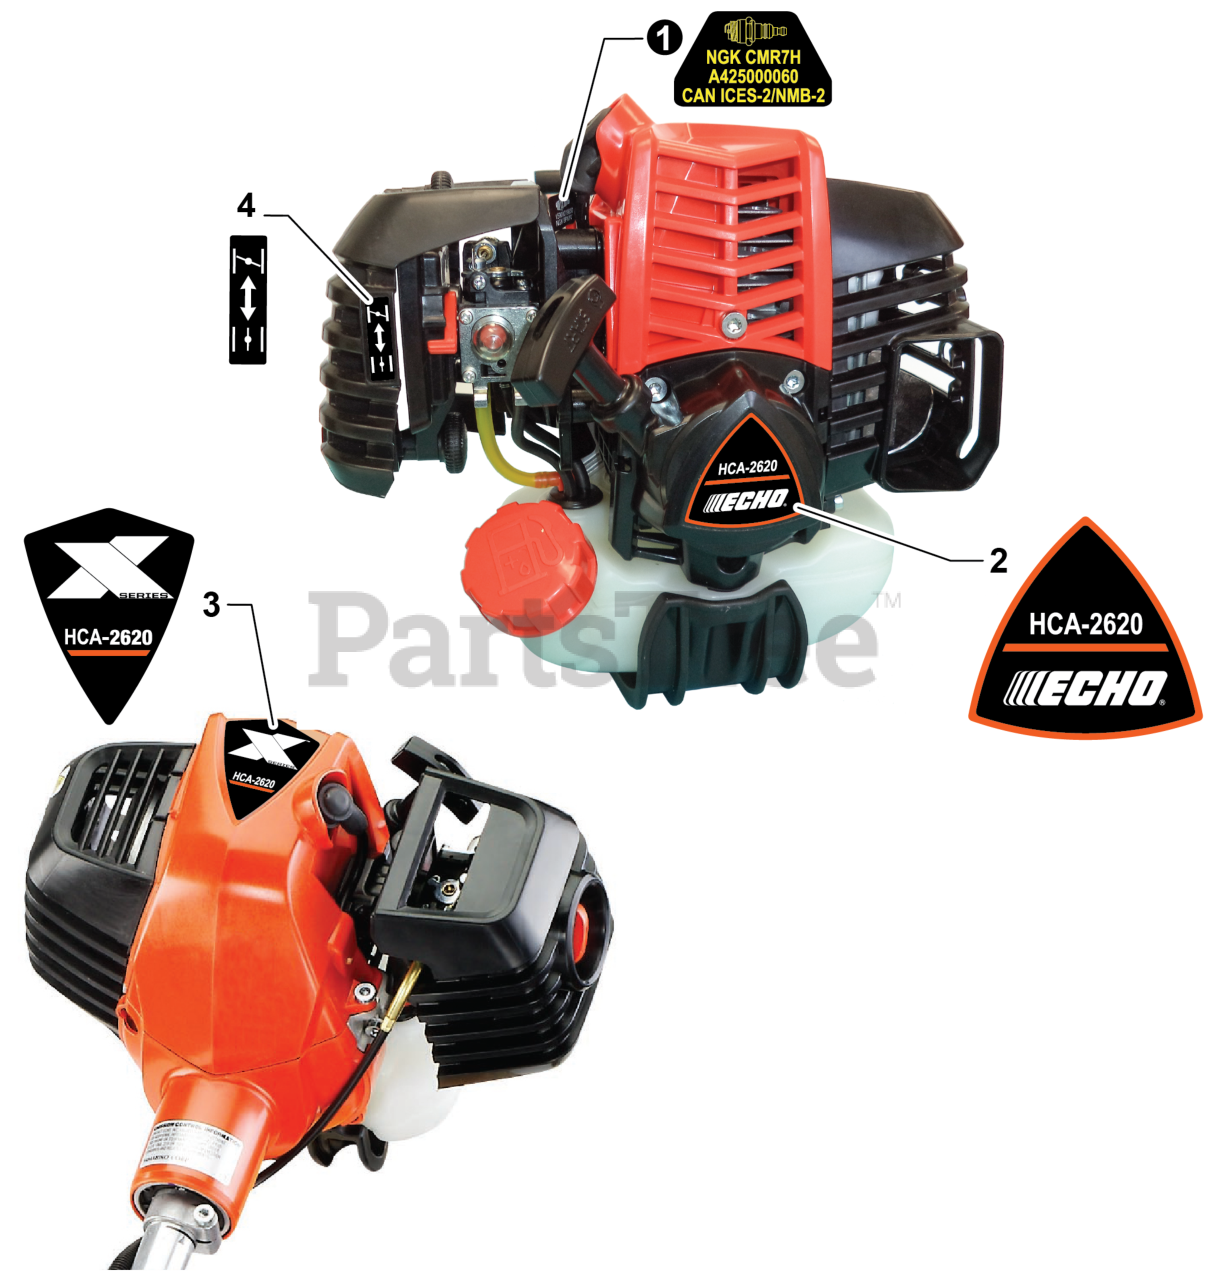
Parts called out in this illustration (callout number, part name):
1	LABEL - SPARK PLUG - CMR7H
2	LABEL - RECOIL STARTER - HCA-2620
3	LABEL - MODEL HCA-2620
4	LABEL - CHOKE
